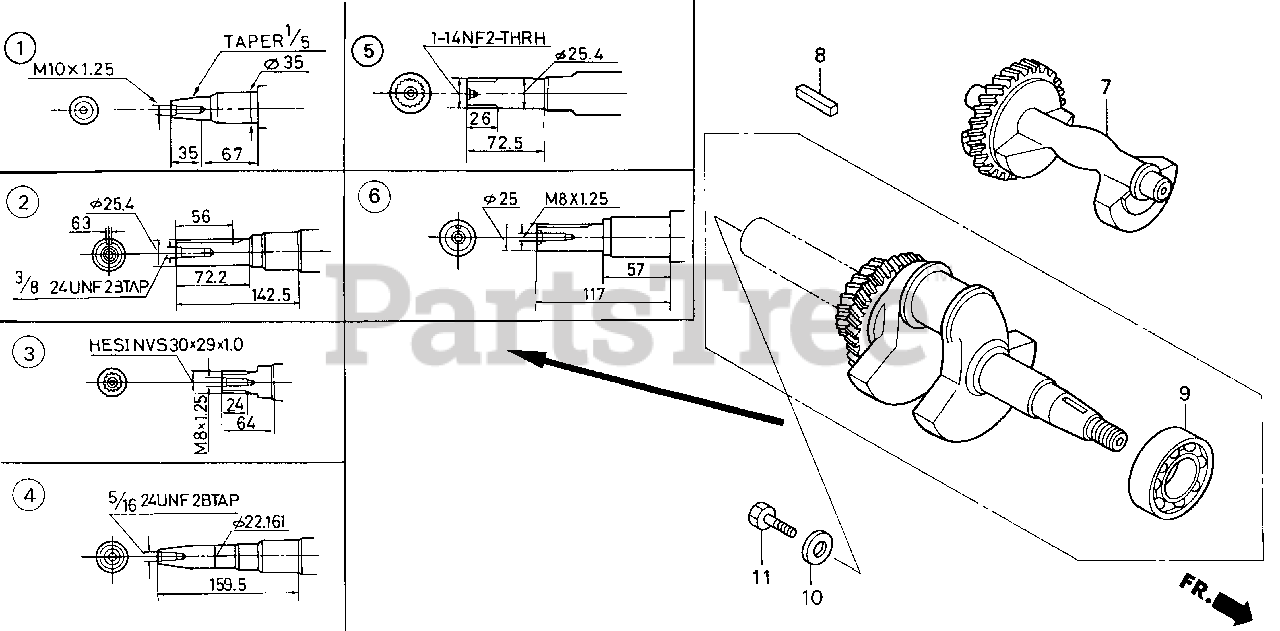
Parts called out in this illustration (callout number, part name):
3	CRANKSHAFT
7	WEIGHT, BALANCER
9	BEARING, RADIAL BALL (6207S)
